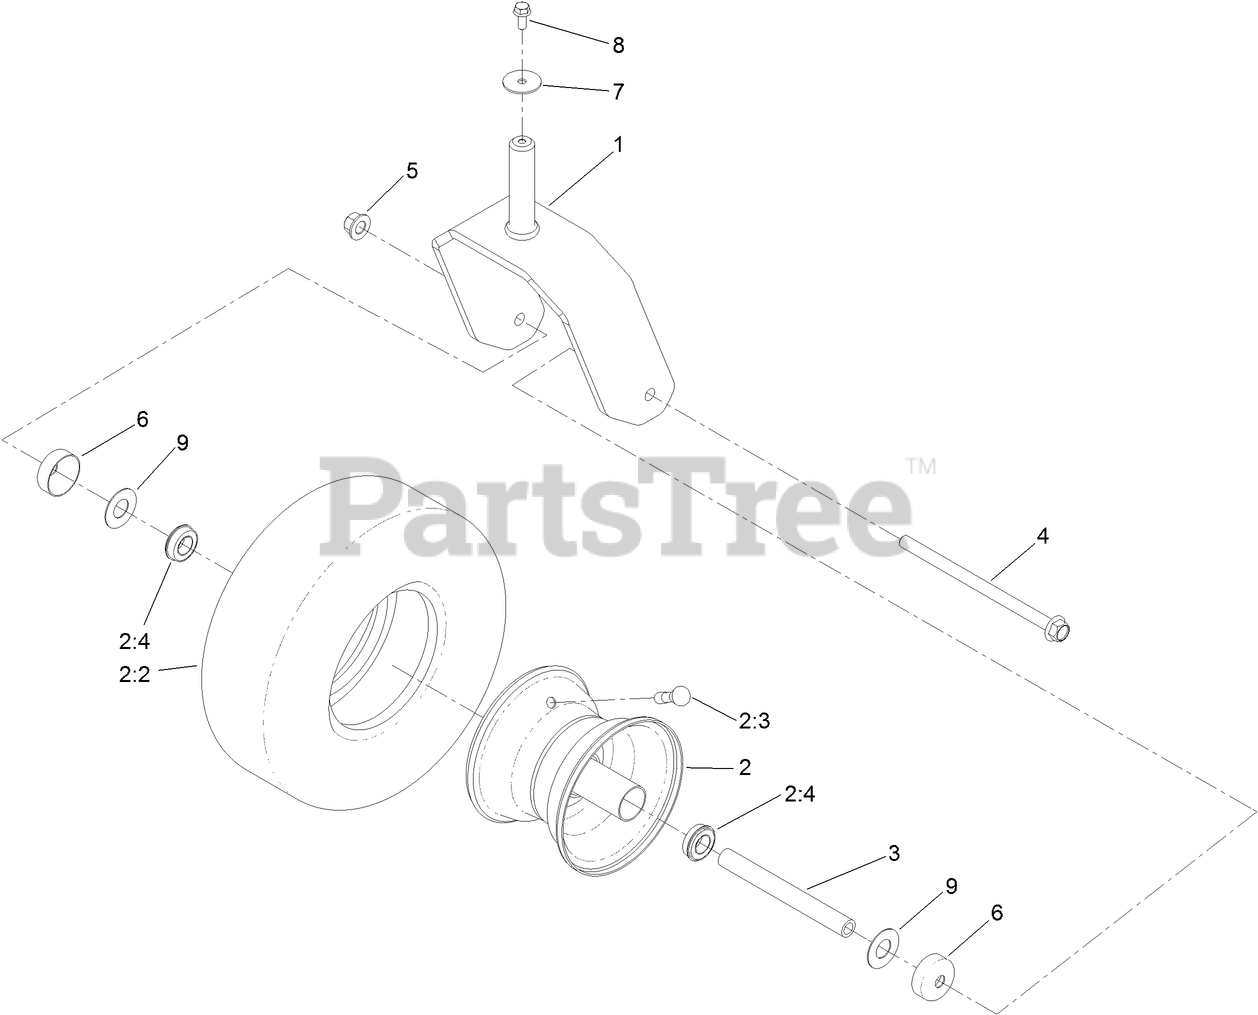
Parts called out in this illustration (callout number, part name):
1	FORK-CASTER
2	TIRE AND WHEEL ASM
2:4	BEARING
2:99	TUBE-INNER
3	SPANNER-WHEEL
4	SCREW-HHF
5	NUT-LOCK
6	GUARD-SEAL
7	WASHER-FLAT
8	SCREW-HHF
9	WASHER
